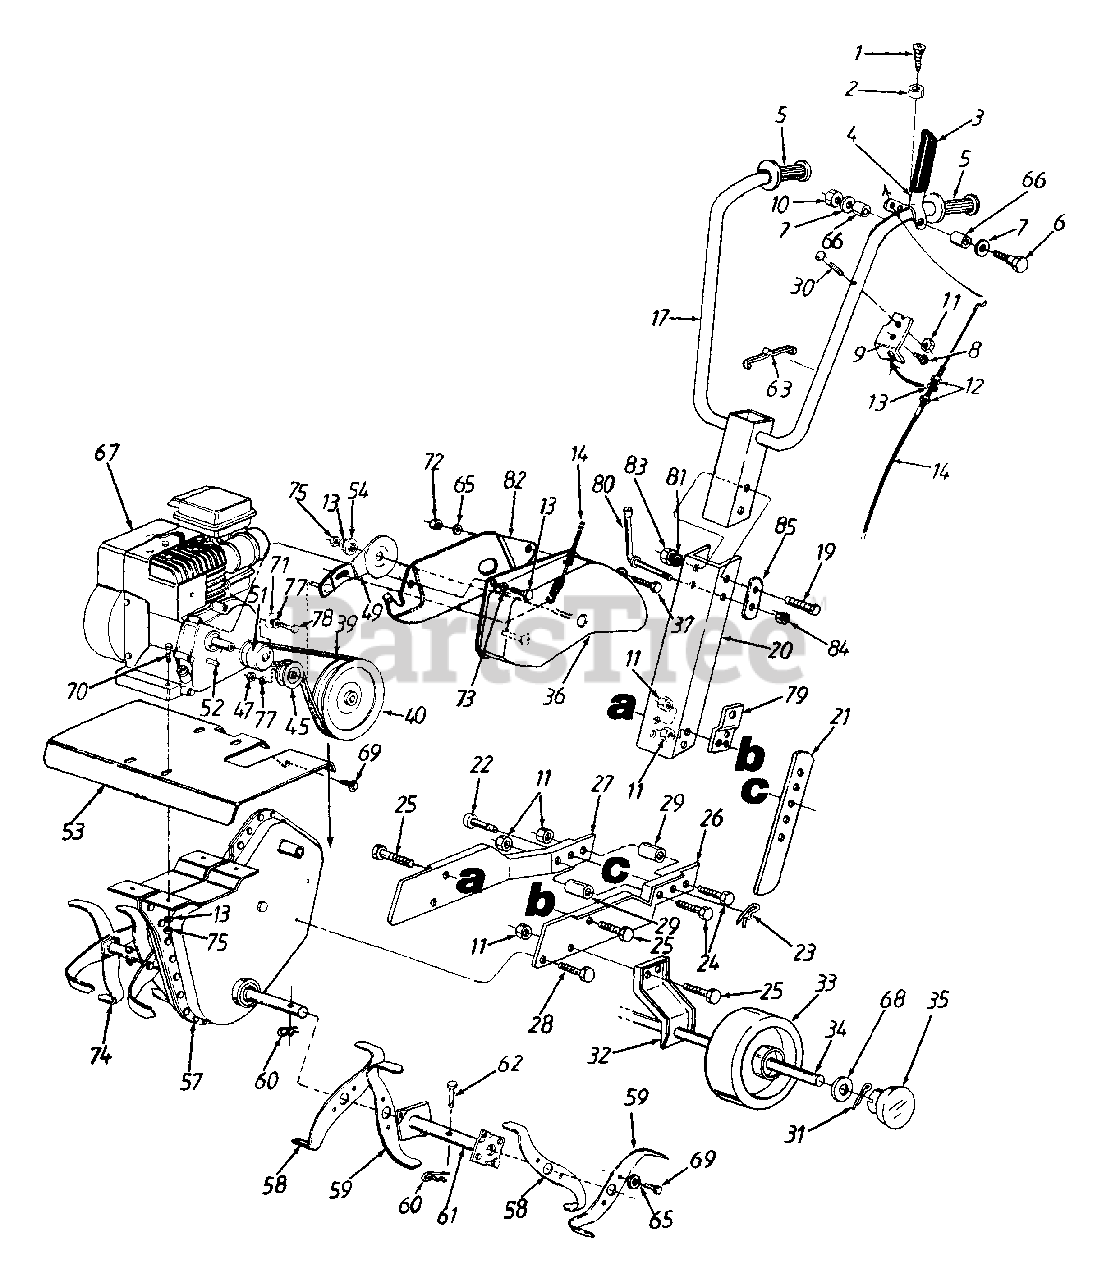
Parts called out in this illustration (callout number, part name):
1	Tap Scr. #10-16 x 1/2" Lg.
2	Rubber Bumper
3	Vinyl Grip
5	Handle Grip
6	Hex Bolt 1/4-20 x 2" Lg.
7	Fl-Wash. 1/4" I.D.
8	Hex Tap Scr. 1/4-20 x 1/2" Lg.
9	Cable Bracket
10	Lock Nut 1/4-20 Thd.
11	Lock Nut 5/16-18 Thd.
12	Hex Jam Nut 5/16-24 Thd.
13	L-Wash. 5/16" I.D.
14	Clutch Control Cable
20	Handle Channel - Frame
21	Depth Stake
22	Clevis Pin
23	Hairpin Cotter
24	Hex Bolt 5/16-18 x 1" Lg.
25	Hex Bolt 5/16-18 x 5/8" Lg.
26	L.H. Frame Half
27	R.H. Frame Half
28	Hex Tap. Scr. 5/16-18 x 1/2" Lg.
29	Spacer
30	Hex Bolt 5/16-18 x 1-1/4" Lg.
31	Cotter Pin
32	Wheel Bracket
33	Wheel - 6"
34	Axle - Wheel
39	V-Belt
40	Pulley - Chain Case
45	Flat Idler Pulley
47	Hex Jam L-Nut 3/8-24 Thd.
49	Idler Arm Ass'y
51	Engine Pulley
52	Square Key 3/16" x .75" Lg.
57	Chain Case Ass'y. Comp.
58	R.H. Tine Blade
63	Cable Tie - Plastic
65	L-Wash 1/4" I.D.
67	Engine
68	Fi-Wash. 3/8" I.D
69	Tap Scr. 1/4-20 x 1/2" Lg.
70	Hex Bolt 5/16-18 x 1-1/2" Lg.
71	Fl-Wash. 3/8" I.D. x 1" O.D.
72	Hex Nut 1/4-20 Thd.
73	Hex Bolt 5/16-24 x .5" Lg.
74	Tine Blade Ass'y. Comp.
75	Hex Nut 5/16-18 Thd.
77	L-Wash. 3/8" I.D.
78	Hex Bolt 3/8-24 x 1" Lg
79	Belt Cover Bracket
80	Handle Adj. Crank
81	FI-Wash. .385" I.D. x .87" O.D.
82	Belt Cover - Rear
83	Hex L-Nut 3/8-16 Thd.
84	Hex Flange L-Nut 3/8-24 Thd.
85	Retainer Bracket
